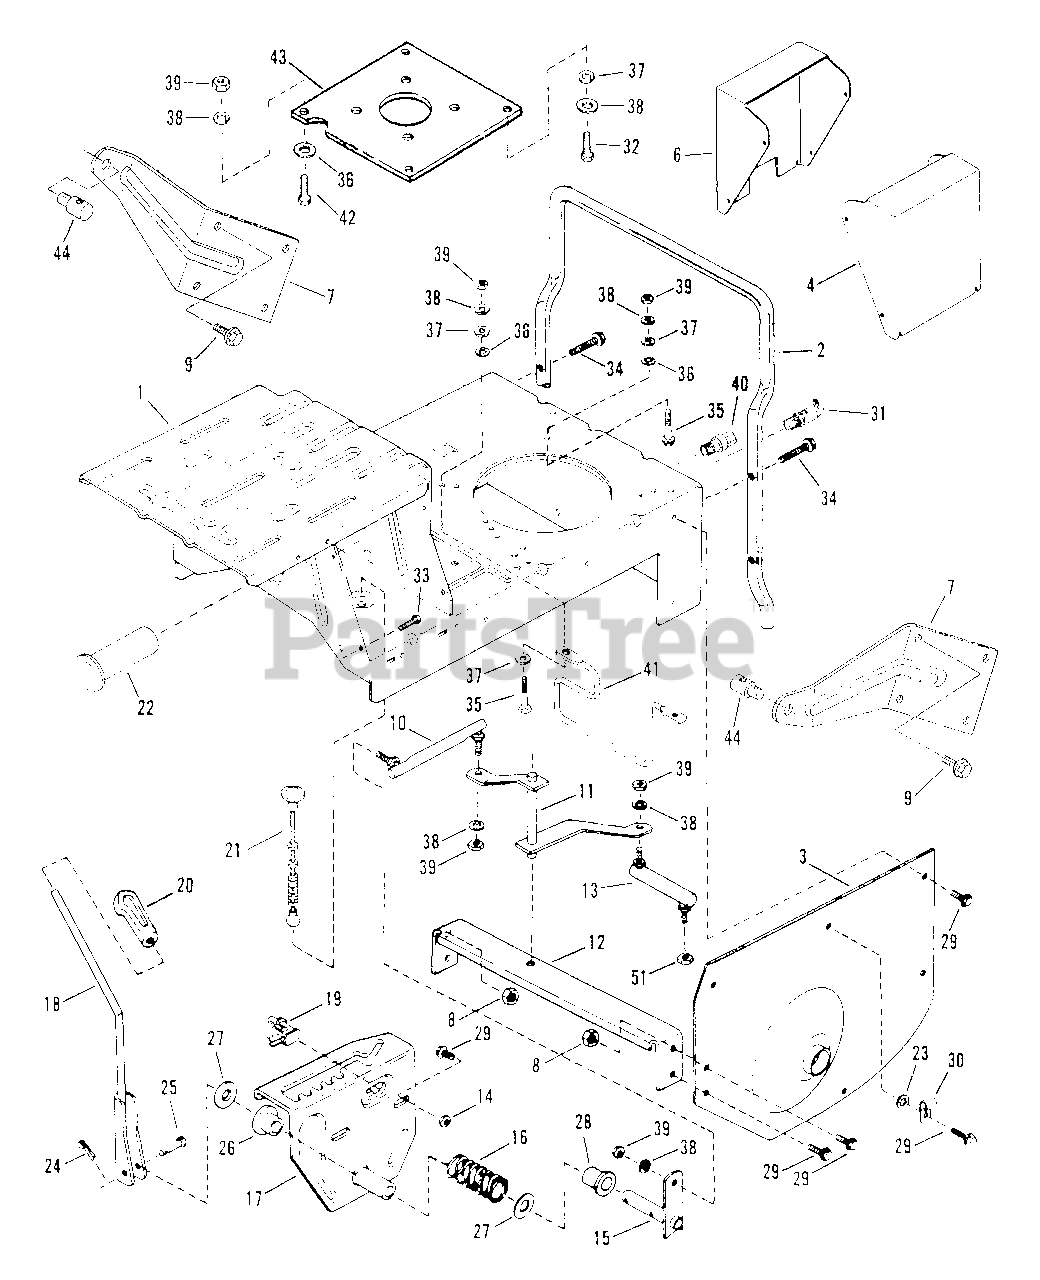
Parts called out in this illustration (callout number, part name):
1	CASE, Main
2	BUMPER, Rear
3	FENDER, Left Hand
4	COVER, Battery
6	COVER, Switch
7	WING, Rear
8	NUT, 5/16-18 Hex Flange Lock
9	SCREW, 5/16-18 x 3/4" Self-Tapping
10	LINK, Shift (Long)
11	ARM, Shift
12	BRACE, Cross
13	LINK, Shift (Short)
14	NUT, 5/16-18 Hex
15	ARM, Shift Handle
16	SPRING, Shift Handle
17	DETENT, Shift
18	HANDLE, Shift
19	SWITCH, Seat
20	KNOB, Shift Handle
21	CABLE, Deck Support
22	BUSHING, Pilot
23	WASHER, 5/16 Internal Tooth Lock
24	PIN, 3/32 x 3/4" Cotter Hair
25	PIN, 1/4 x 1-3/4" Tapered Clevis
26	BUSHING, Nylon
27	WASHER, Thrust
28	BUSHING, Nylon
29	SCREW, 5/16-18 x 5/8" Self-Tapping
30	CLIP, Wire
31	DRAIN, Oil (1/4 Turn)
32	SCREW,
33	FASTENER, 1/4 x 3/4 Ratchet
34	SCREW, 5/16-18 x 1-1/2" Self-Tapping
35	SCREW, 5/16-24 x 1-3/4" Hex Head Cap
36	RETAINER, 5/16 Bolt
37	WASHER, 5/16" Flat
38	WASHER, 5/16" Split Lock
39	NUT, 5/16-24 Hex
40	DRAIN, Oil (Short)
41	GUIDE, Belt
42	SCREW, 5/16-24 x 1" Hex Head Cap
43	PLATE, Engine
44	SWIVEL
51	NUT, 5/16-24 Hex Flange Lock
